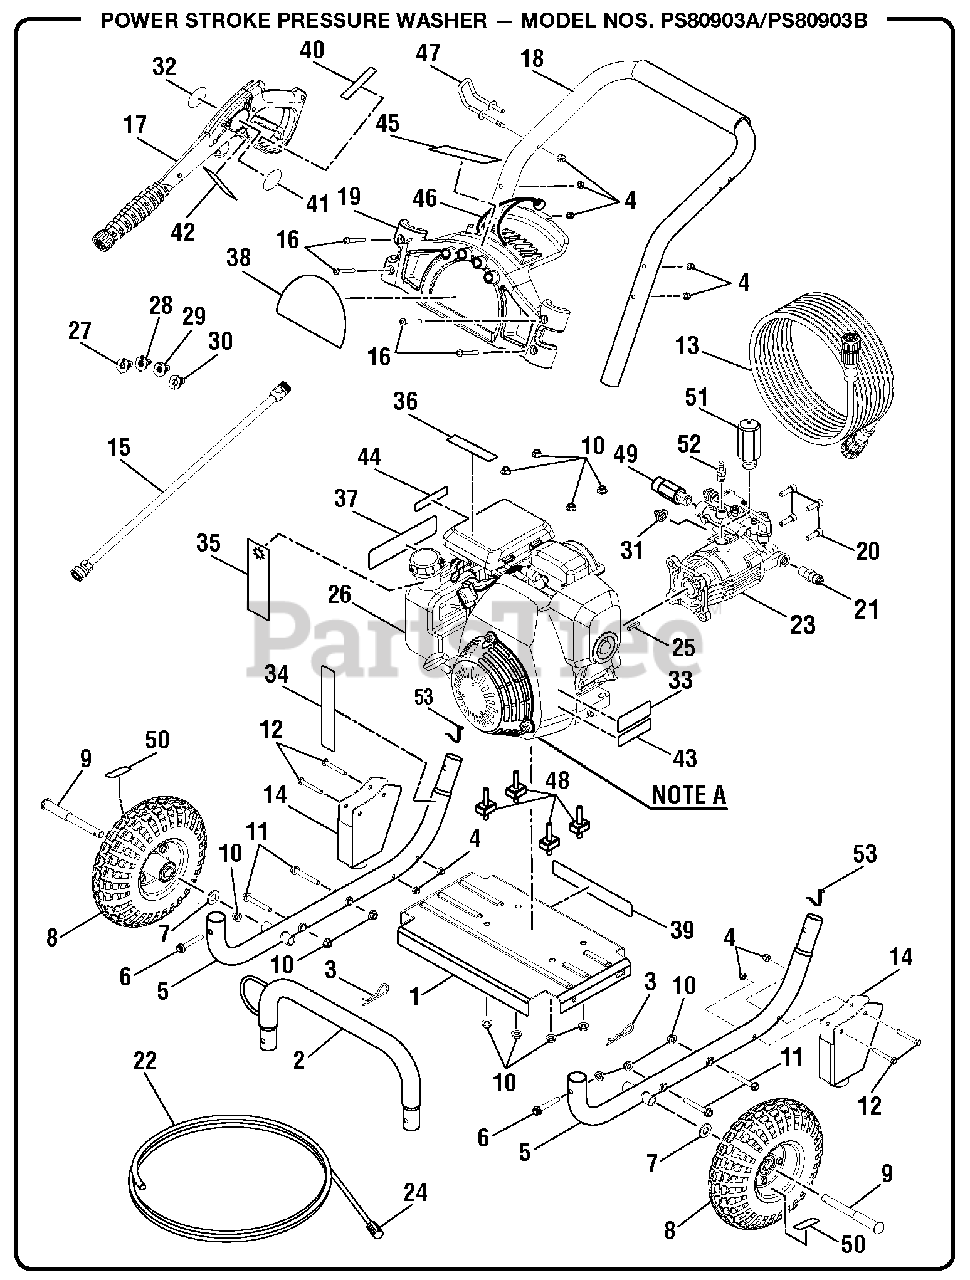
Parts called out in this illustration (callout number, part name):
1	Engine Plate
2	Front Frame
3	Hitch Pin
4	Lock Nut (1/4-20)
5	Main Frame Assembly
6	Bolt (M8 x 50 mm)
7	Washer (1/2 in.)
8	Wheel (10 in. x 3 in.)
10	Lock Nut (M8 x 1-1/4 in.)
11	Bolt (M8 x 55 mm)
12	Bolt (1/4-20 x 52 mm, Hex Hd.)
13	High Pressure Hose (25 ft.)
14	Rear Foot Assembly
15	Spray Wand
16	Screw (1/4-20 x 2 in., Torx)
17	Trigger Handle Assembly
18	Handle Assembly
19	Wand Holder
20	Bolt (5/16-24 x 23 mm)
21	Thermal Release Valve
22	Injection Hose
23	Himore Pump
23	AR Pump
25	Output Shaft Key
26	160cc Honda Short Shaft Engine
26	160cc Honda Engine
27	0deg Nozzle
28	40deg Nozzle
29	25deg Nozzle
30	Detergent Nozzle
31	Filter Screen
32	Wand Label
33	Hot Surface Label
34	Pump Quick Start Label
35	Hang Tag (Engine Oil Fill)
36	Engine Quick Start Label
37	Warning Label
38	Performance Label
39	Data Label
40	Wand Label (Max Rating)
41	Trigger Handle Warning Label
42	Warning Label (French/Spanish)
43	Warning Label (Combustion)
44	Warning Label (Inquiries)
45	Label (Powered by Honda)
46	Bungee Cord and Bead Assembly
47	Wand Holder
48	Engine Isolator
49	Outlet Tube
50	Wheel Label (25 psi max)
52	Detergent Suction Kit
53	Lock Button w/Spring Clip
